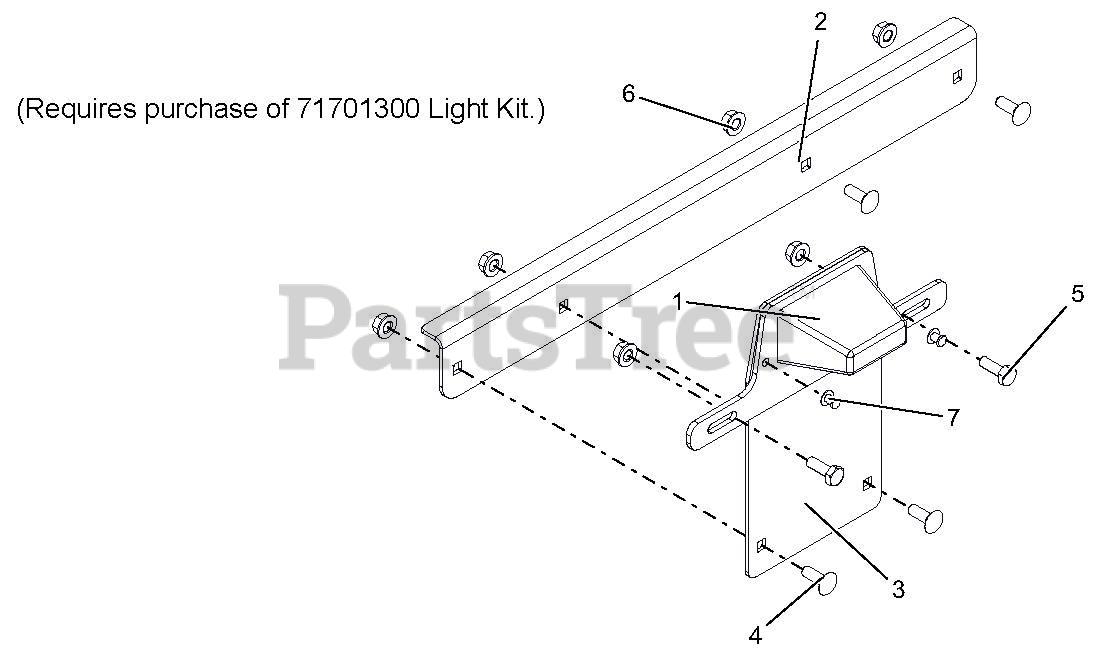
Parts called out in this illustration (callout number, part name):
1	LICENSE PLATE BRACKET W/ LIGHT
2	BRKT, SPLITTER LICENSE PLATE
3	SUPPORT, LICENSE PLATE BACK
4	@BLT-RDHDSQNK .25-20X.75 G5YZ
5	@BLT-HEX .25-20X.75 GR5 YWZC
6	@NUT-LK-TOP-FLG .25-20 YWZC
7	RVT-POP .187 YZ
